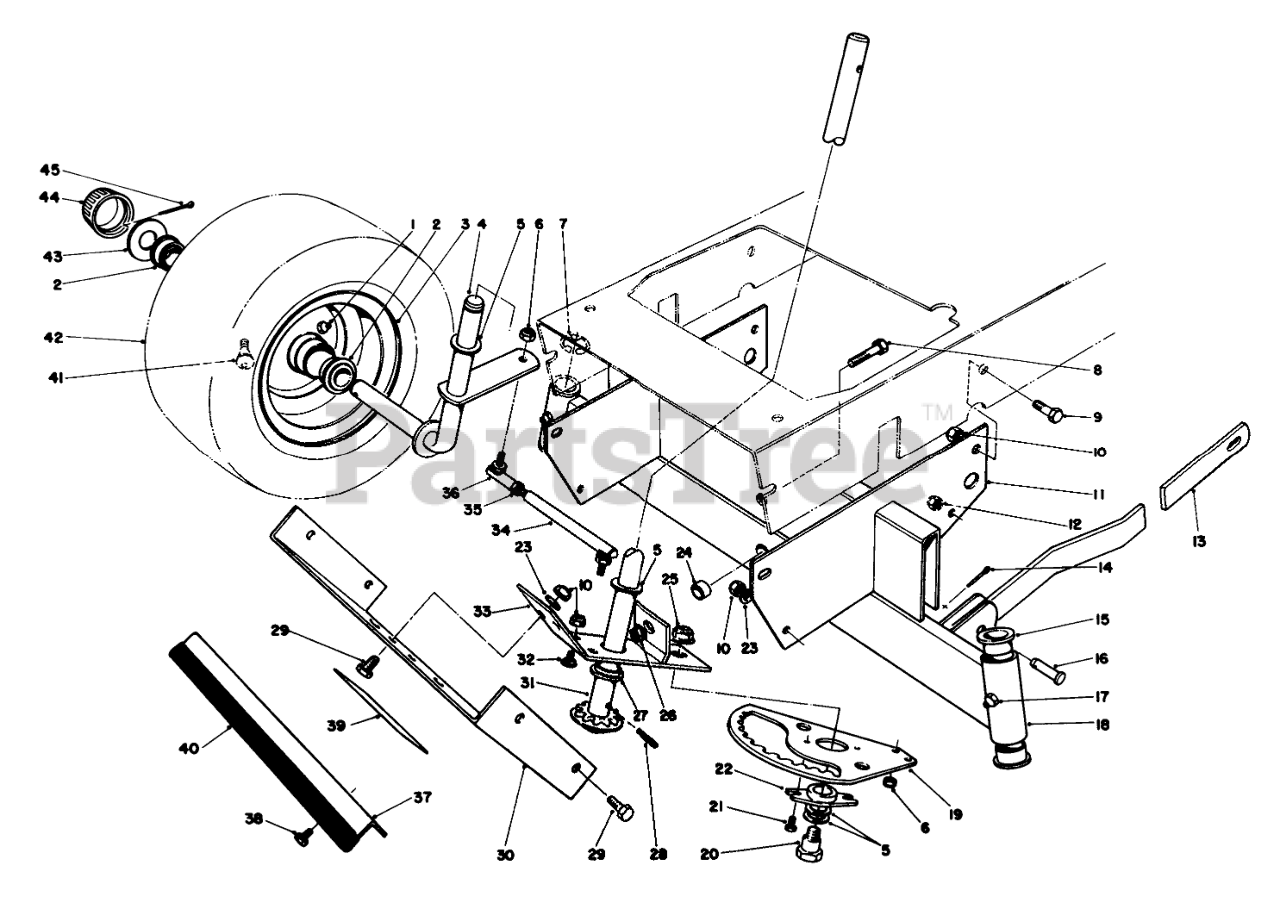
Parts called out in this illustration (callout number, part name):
1	FITTING-GREASE
2	Bearing
4	Spindle RH
5	WASHER-THRUST
6	NUT-LOCK
7	E-RING
8	SCREW-HH
9	SCREW-HH
10	NUT-LOCK, NI
11	Support
12	NUT-LOCK, CONE
13	Arm-Suspension, Front
14	PIN-COTTER
15	BEARING-FLANGE
16	PIN-CLEVIS
17	Fitting-Grease
18	Axle-Front (Incl. Ref. #15 & 17)
19	STEERING RACK B
21	SCREW
22	BUSHING-SECTOR
23	WASHER-PLAIN
24	SPACER-AXLE, FRONT
25	NUT-HF
26	NUT-HF
27	BEARING-FLANGE
28	PIN-ROLL, SLOTTED
29	SCREW-HH
30	Cover-Front
31	STRG SHAFT WA
32	SCREW-CARR
33	Bracket-Steering Rack (Incl. Ref. #27)
34	Tie Rod-Steering (Incl. Ref. #35 & 36)
35	NUT-JAM
36	JOINT-BALL
37	FRONT GUARD R
38	SCREW-HWHTF
39	Decal-Warning
40	TRIM-FRONT GUARD
41	STEM-VALVE
42	TIRE,PNEU.11X4.00X5
43	WASHER-PLAIN
44	CAP-HUB
45	PIN-COTTER
